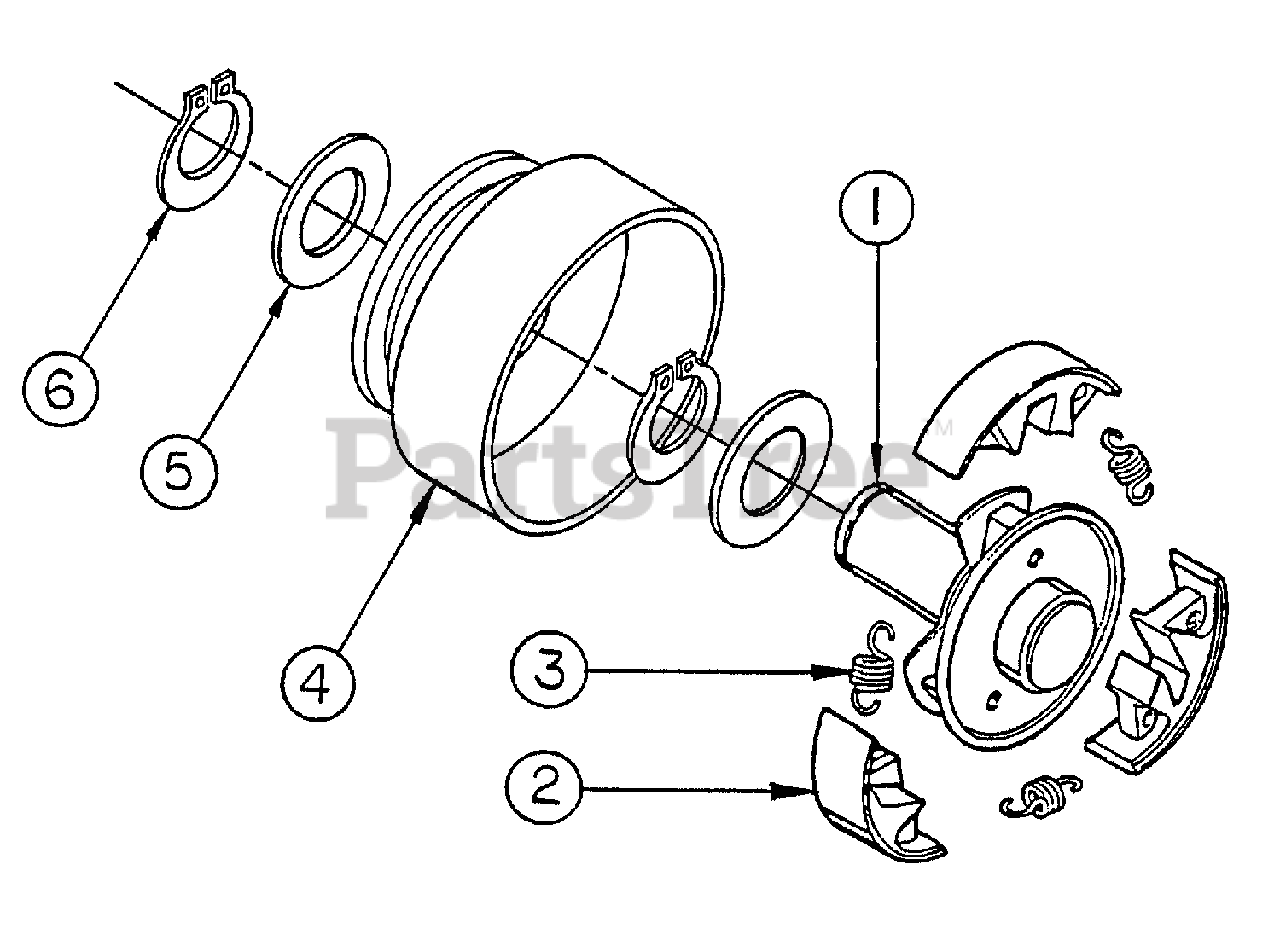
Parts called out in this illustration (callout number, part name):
1	Hub Assembly
3	Spring
4	Drum Assembly
5	Washer
6	Retaining Ring
